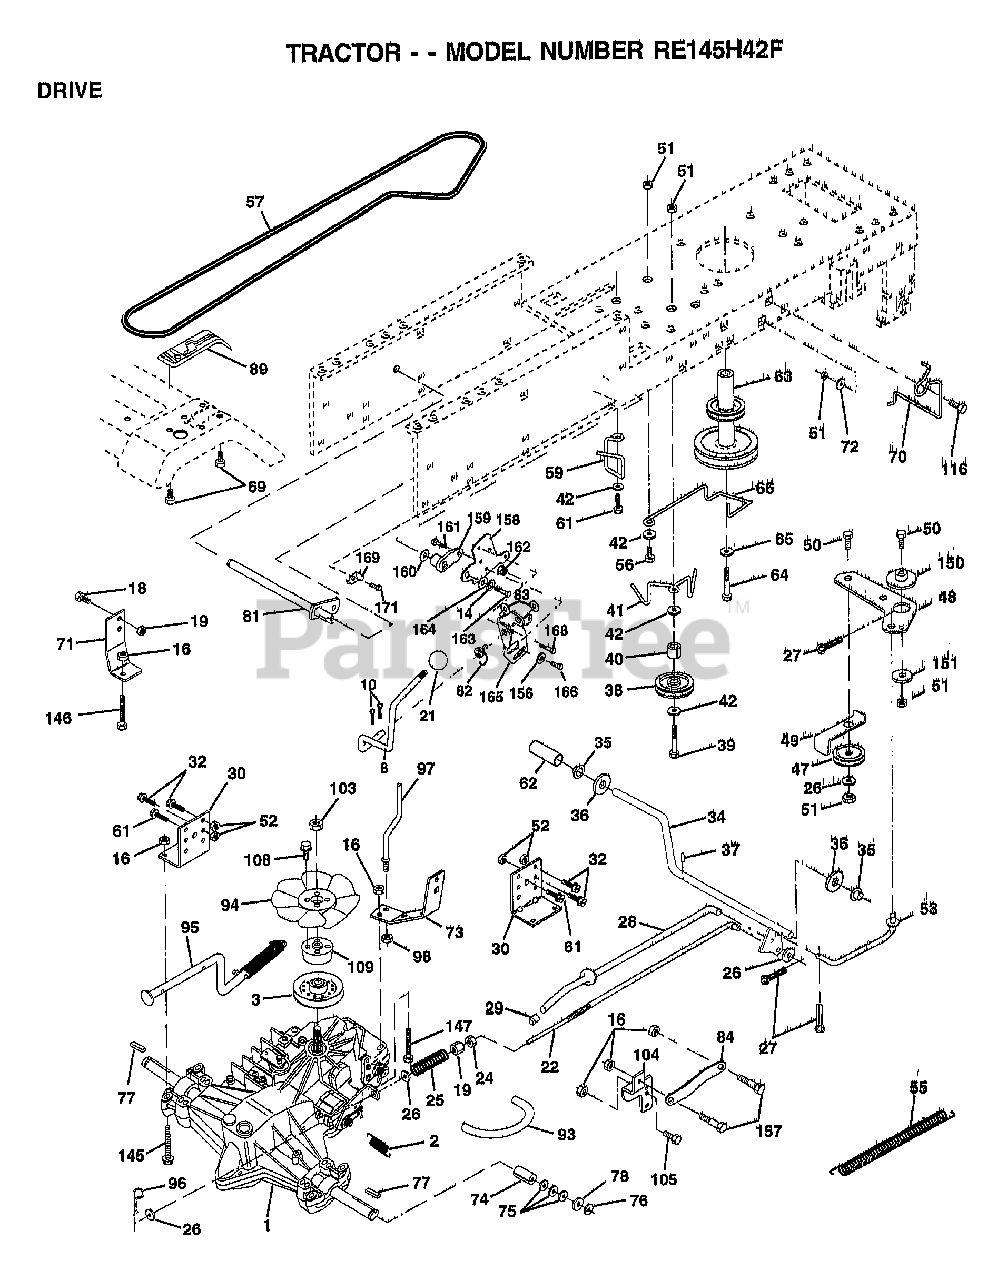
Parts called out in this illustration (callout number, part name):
2	SPRING RET BRAKE
3	PULLEY.4.20.HYDRO
8	ROD.SHIFT.FENDER.ADJ.LT.CRD
10	PIN COTTER 1/8
14	LOCKWASHER
16	NUT
18	BOLT
19	NUT
21	KNOB T (1/2-HOLE)
22	ROD.BRAKE.HYDRO.
24	NUT
25	SPRING ROD LT
26	WASHER
27	COTTER PIN
28	ROD.BRAKE.PARK.LT
29	PLUNGER CAP T
30	TRANSAXLE MTG BKT
32	BOLT
34	SHAFT ASM-PEDAL F
35	NYLON BEARING
36	WASHER LT
38	FLAT IDLER PULLEY
39	BOLT
40	SPACER T
41	"KEEPER,BELT.IDLER FLAT"
42	WASHER
48	BELLCRANK.CLUTCH
49	RETAIN BELT
53	"LINK, CLUTCH T"
55	"SPRING, RETURN LT"
57	BELT-V.HYDR.84.61
59	KEEPER BELT CNTSP
61	SCREW
62	PEDAL COVER T
63	PULLEY.ENGINE
64	BOLT.HEX.7/16-20X4.GR.5
65	LOCKWASHER
66	KEEPER-BELT
69	SCREW HEXWSH H-L
70	KEEPER BELT ENG
71	STRAP.TORQ.LH.HYD
72	WASHER
73	STRAP.TORQ.RH.HYD
74	SPACER SPLIT
75	WASHER
76	E-RING LT
77	SQUARE KEY
78	WASHER
81	SHAFT ASM.CROSS
82	"SPRING,TORSION"
83	WASHER
84	LINK.TRANSAXLE.HYDR
89	CONSOLE.SHIFT.LT
93	"LINE FUEL HYD 4"""
94	"FAN 7"" HYDRO"
95	CONTROL.ASM.BYPASS.HYDRO.99
96	RETAINER M
97	KEEPER.BELT.RH.HY
98	NUT
104	ARM.CONTROL.PUMP
105	SCREW CAP 5/16-18
108	SCREW.HXHD.10-20
109	ADAPTOR.FAN.HYDRO
116	BOLT RDHD 3/8-16
145	BOLT.HEX.FLGHD
146	BOLT.HEX.FLGHD.
147	BOLT.HEX.FLGHD
150	BUSHING.BELLCRANK.GRD.DR
151	WASHER
156	WASHER.SRRTD.5/16
157	"BOLT,SHOULDER"
158	BRKT.SHIFT.MOUNT
159	HUB.SHIFT
160	WASHER
161	BOLT T
164	WASHER.5/8X.281X10GA
165	BRKT.PIVOT.LEVER
166	SCREW.5/16-18X5/8
168	BOLT.SHOULDER.5/16-18X.561
169	PLATE.FASTENING
171	SCREW LT
